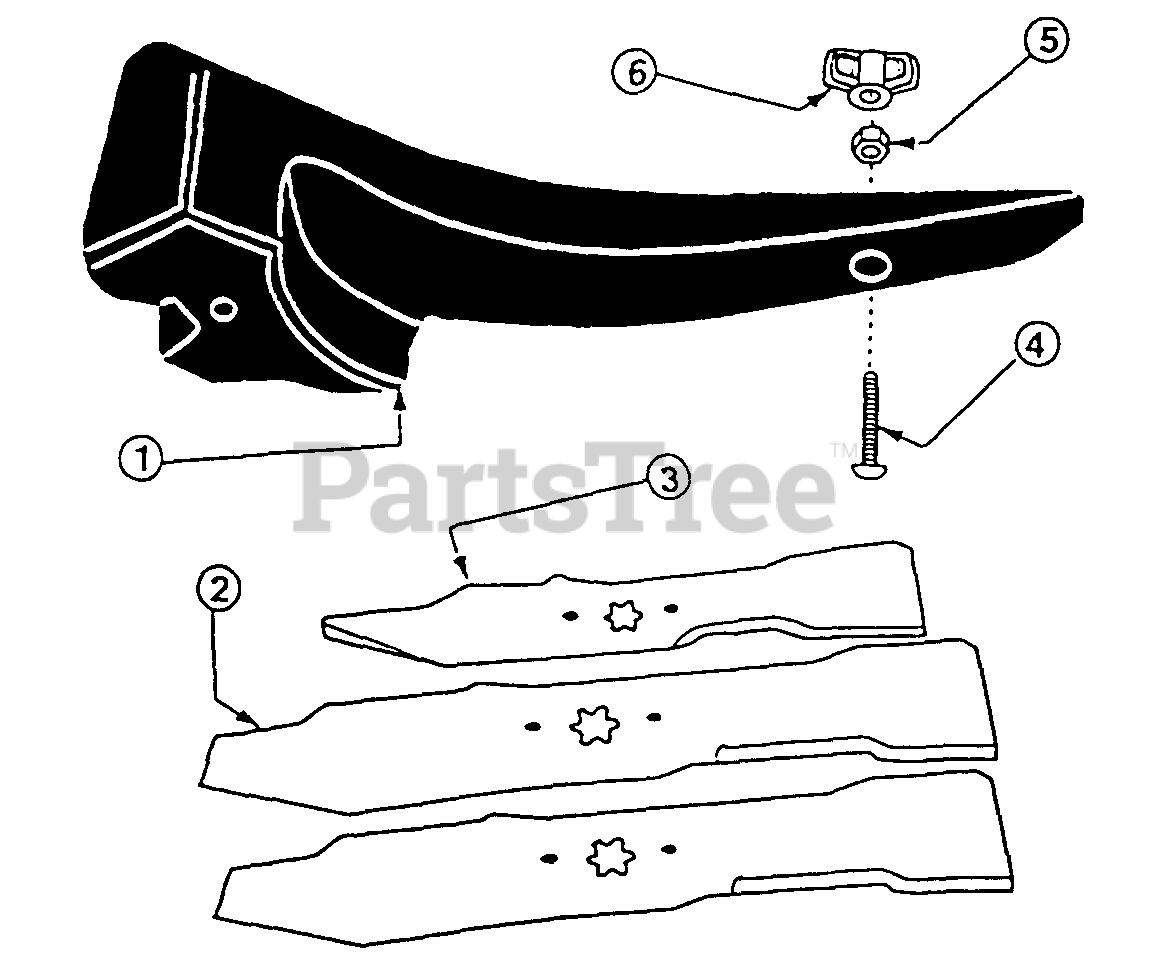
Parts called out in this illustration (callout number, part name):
1	Mulching Plug
2	16.28" 3 in 1 Blade
3	14.88" 3 in 1 Blade
4	Machine Screw (1/4")
5	Hex Locking Nut (1/4")
6	Wing Nut (1/4")
